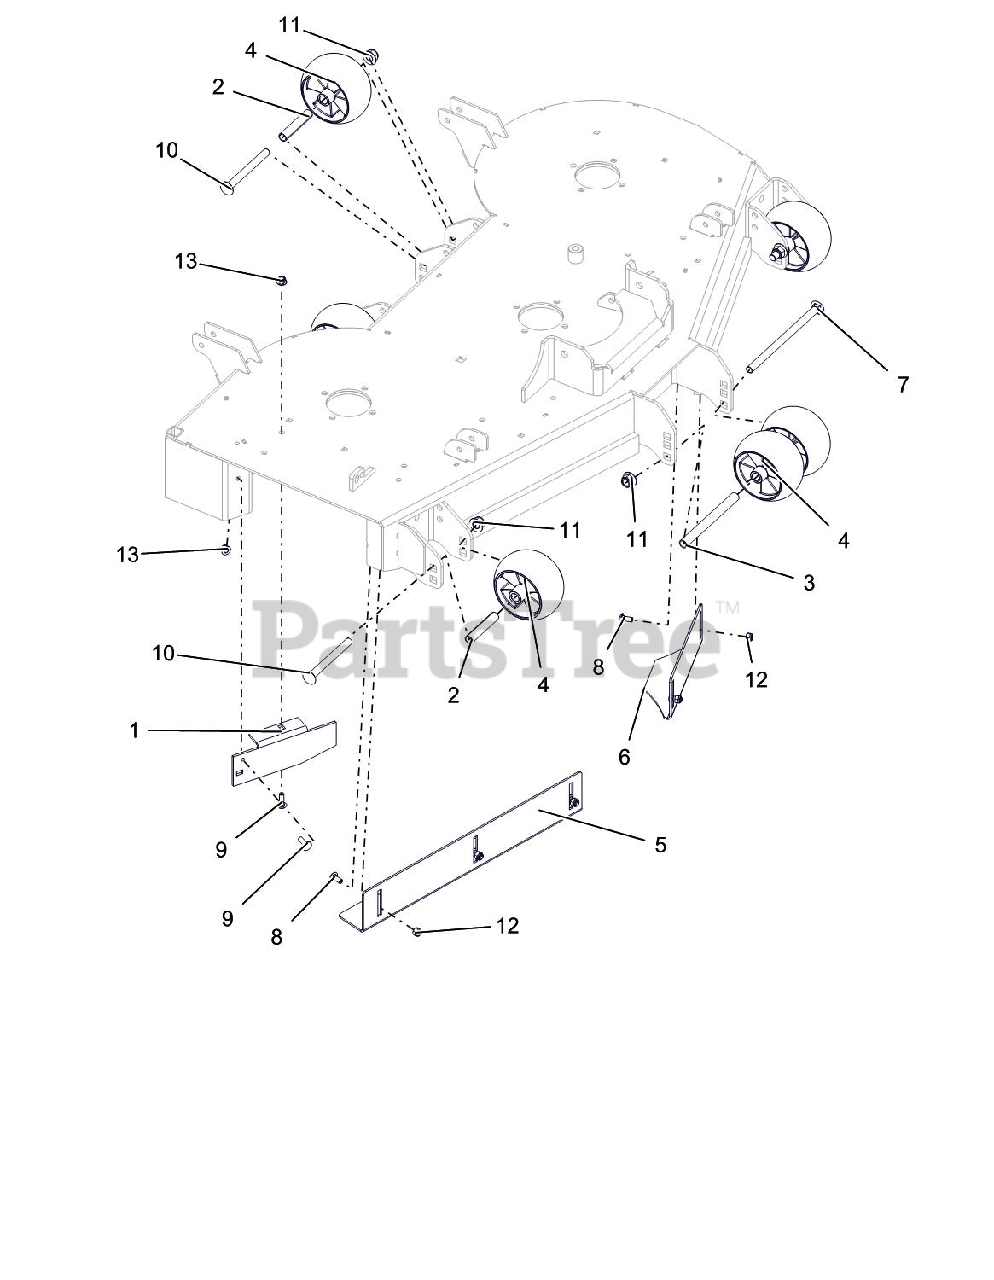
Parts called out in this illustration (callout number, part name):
1	44"-48" SIDE DISCH BAFFLE -RED
2	.510X.625X3.35 SPACER-LOW FILM
3	.510X.625X6.50 SPACER-LOW FILM
4	ANTI-SCALP WHEEL - 5X3 CTR
5	BAFFLE-48" RH VACUUM
6	BAFFLE-44"/48" LH VACUUM
7	@BLT-RDHDSQNK .50-13X8.50 G5YZ
8	@BLT-RDHDSQNK .31-18X.75 G5YZ
9	@BLT-RDHDSQNK .31-18X1.00 G5YZ
10	BLT-RDHDSQNK .50-13X5.00 GR5YZ
11	@NUT-LK-NYL-FLG .50-13 YWZC
12	@NUT-LK-NYL .312-18 YWZC
13	@NUT-LK-NYL-FLG .31-18 YWZC
